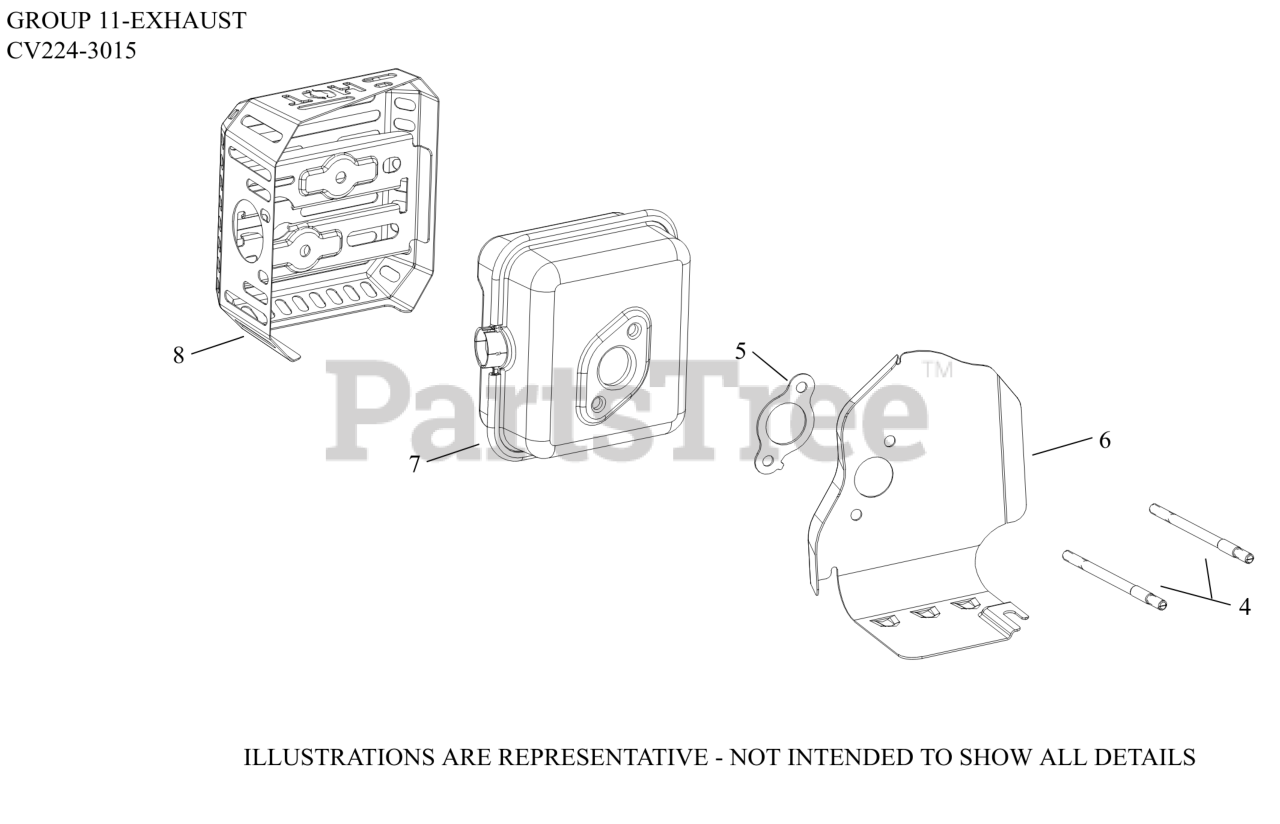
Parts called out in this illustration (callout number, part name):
4	STUD, EXHAUST (M6)
5	GASKET, MUFFLER (HEAT DEFLECTOR)
6	BAFFEL, BARREL
7	MUFFLER, ASSEMBLY
8	GUARD, MUFFLER ASSEMBLY
